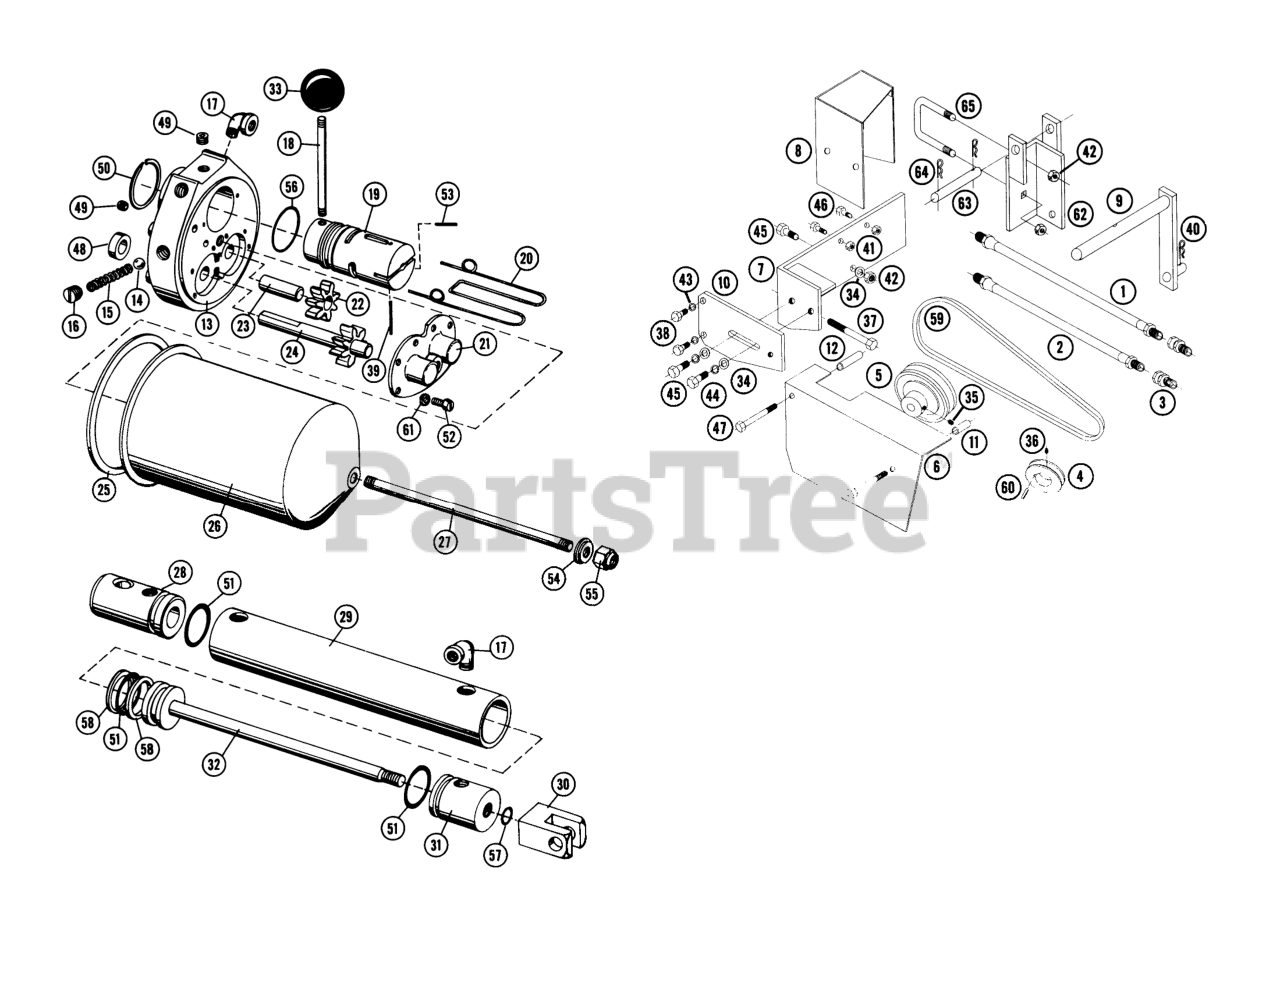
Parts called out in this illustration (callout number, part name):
1	Hose 1/4" x 27" long
2	hose 1/4" x 23" long
3	1/4" NPT Pipe Couplings
4	Pulley 2 1/4 Dia.
5	Pulley
6	Belt Guard
7	Pump Mounting Bracket
8	Instrument Mounting Bracket
9	Lift Link
10	Spacer
11	Pipe Spacer 1/4 x 2 1/8 lg
12	Washer-Seal
13	60-950-01 GIL 6HP 2
14	Ball
15	Spring
16	Plug
17	Street Elbow 1/4 NPTF
18	Handle
19	Spool Valve
20	Spring
21	Cover
22	Gear
23	Shaft
24	Drive Shaft Ass-y.
25	Gasket
26	Reservoir
27	Stud
28	Head
29	Tube
30	Clevis
31	Guide
32	Piston Rod Ass-y.
33	Knob
34	Washer, 3/8
35	Snap Ring
36	Set Screw 1/4-20 x 1
37	Cap Screw, 3/8 x 2 1/2
38	Hex Rd. Cap Screw 5/16-18 x 5/8
39	1/8 x 1 1/4 Roll Pin
40	Hair Pin Cotter
41	1/4-20 Lock Nut
42	Nut
43	Lock Washer 5/16
44	Lockwasher 3/8
45	Bolts 3/8-16 x 3/4
46	1/4-20 x 5/8 Hex Hd. Cap Screw
47	Hex Head Cap Screw 5/16-18 x 2 1/2
48	Seal
49	Allen Hd. Pipe Plug 1/8
50	Snap Ring
51	O Ring
52	Cover Screw #10-32 x 7/16
53	Roll Pin 5/32 x 5/8
54	Washer
55	Hex Head Lock Nut 3/8-16
56	O Ring
57	O Ring
58	Back Up Washer
59	"V" Belt 3L-510
60	Key 1/4 x 1/4 x 1
61	Lock Washer #10-32
62	Cylinder Support
63	Pin
64	Hair Pin Cotter
65	U-Bolt
